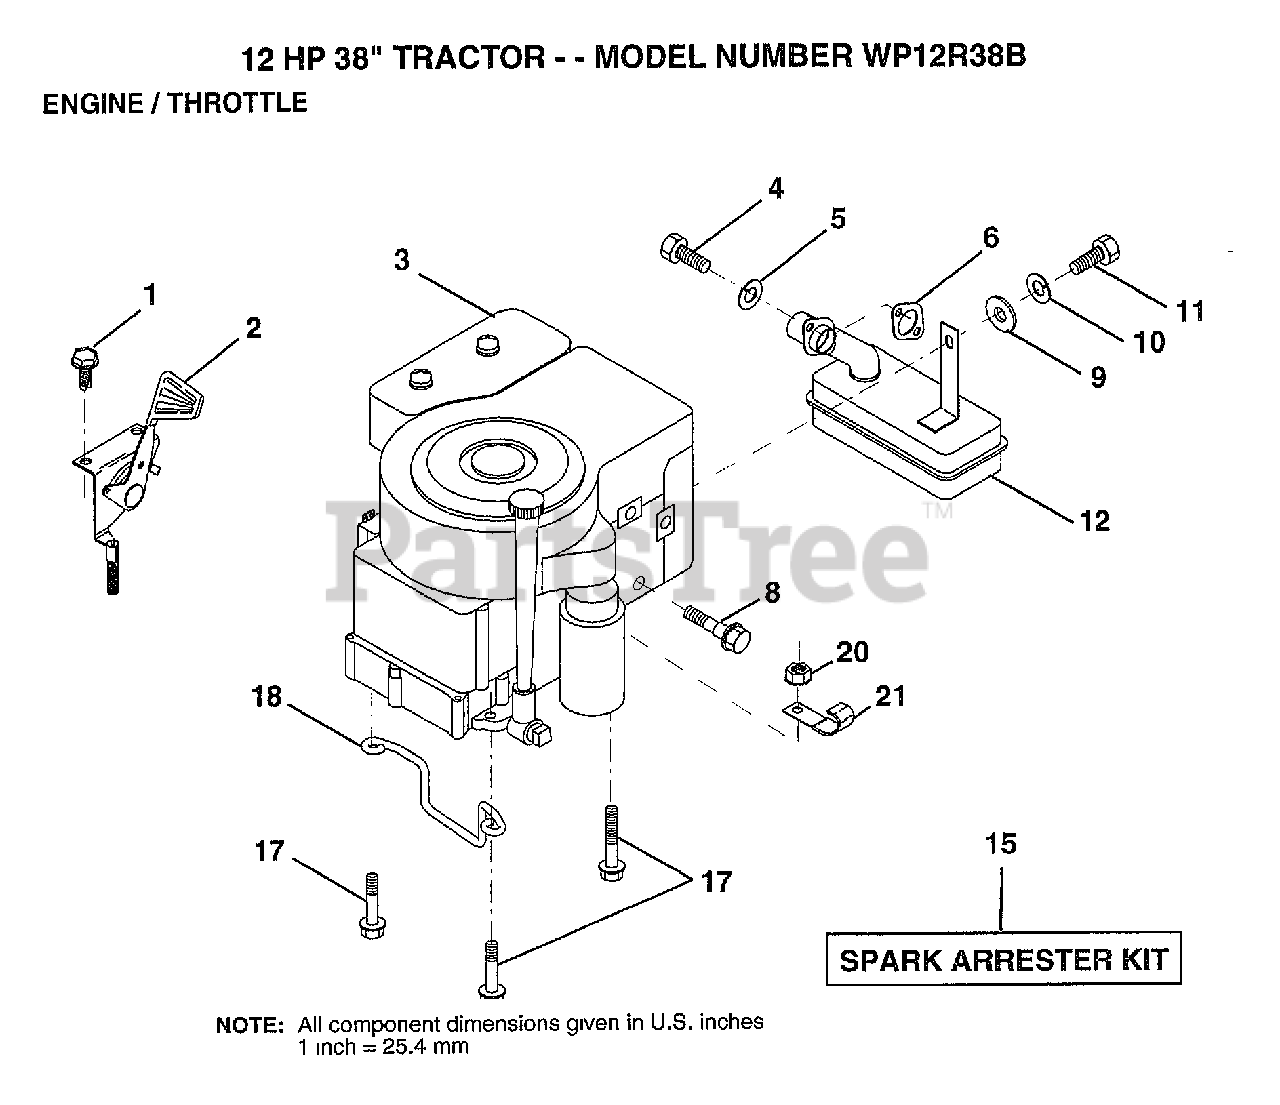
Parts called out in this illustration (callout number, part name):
1	SCREW
2	"CONTROL,THROTTLE"
4	SCREW
5	LOCKWASHER
8	BOLT T
10	LOCKWASHER
12	MUFFLER
17	SCREW LT
18	"KEEPER,DR BELT GR"
20	NUT
21	CLIP T
